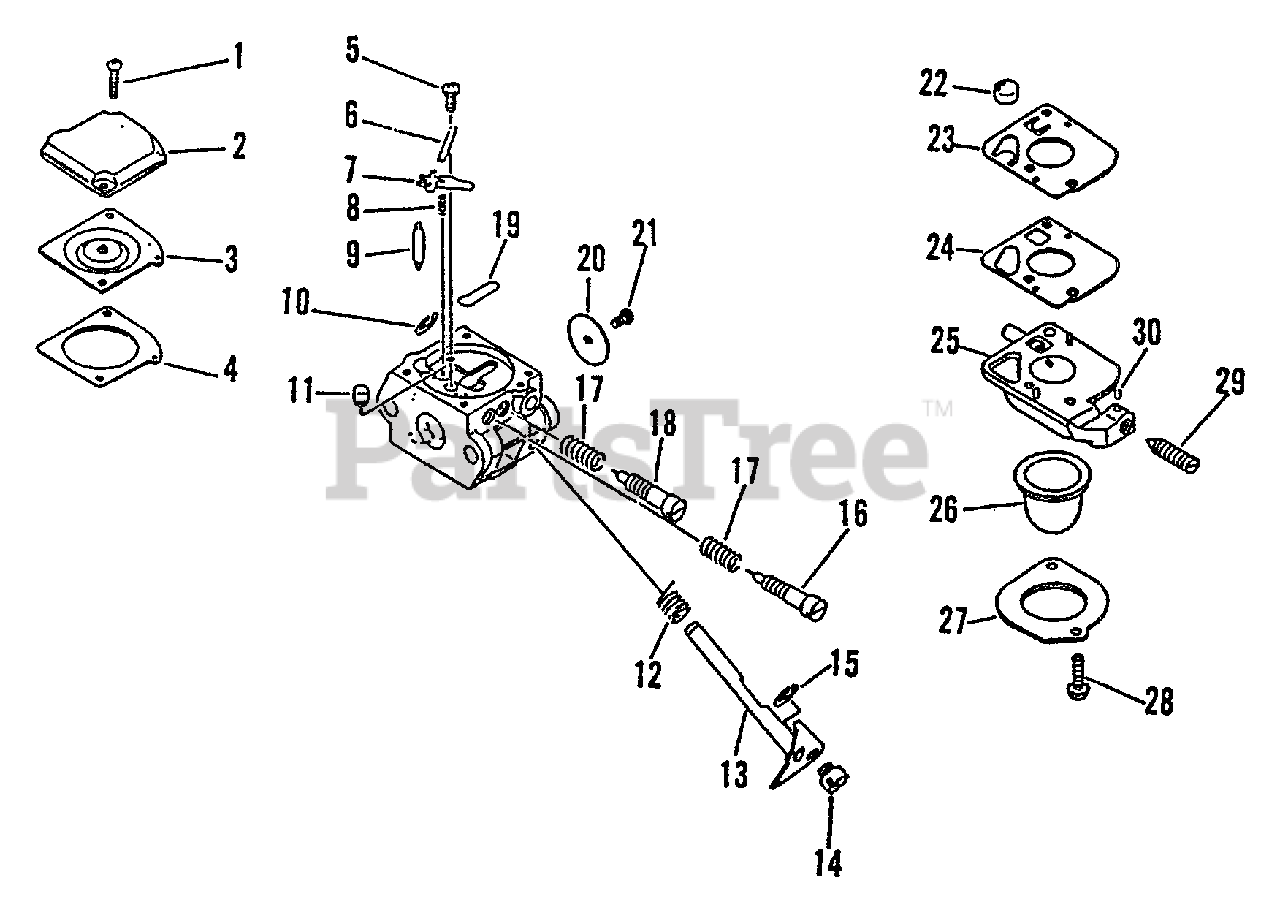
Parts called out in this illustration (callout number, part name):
2	COVER, DIAPHRAGM
3	DIAPHRAGM
4	GASKET, METERING
6	PIN
7	LEVER, METERING
8	SPRING
9	VALVE, NEEDLE
11	NOZZLE, CHECK VALVE
12	SPRING, THROTTLE RETURN
13	SHAFT, THROTTLE
16	NEEDLE, IDLE
17	SPRING, NEEDLE
18	NEEDLE, HIGH SPEED
19	PLUG, WELCH
20	VALVE, THROTTLE
22	STRAINER
25	BODY ASSY, PURGE
26	BULB, PURGE
27	RETAINER
29	SCREW, IDLE ADJUST
30	PIECE, FRICTION
